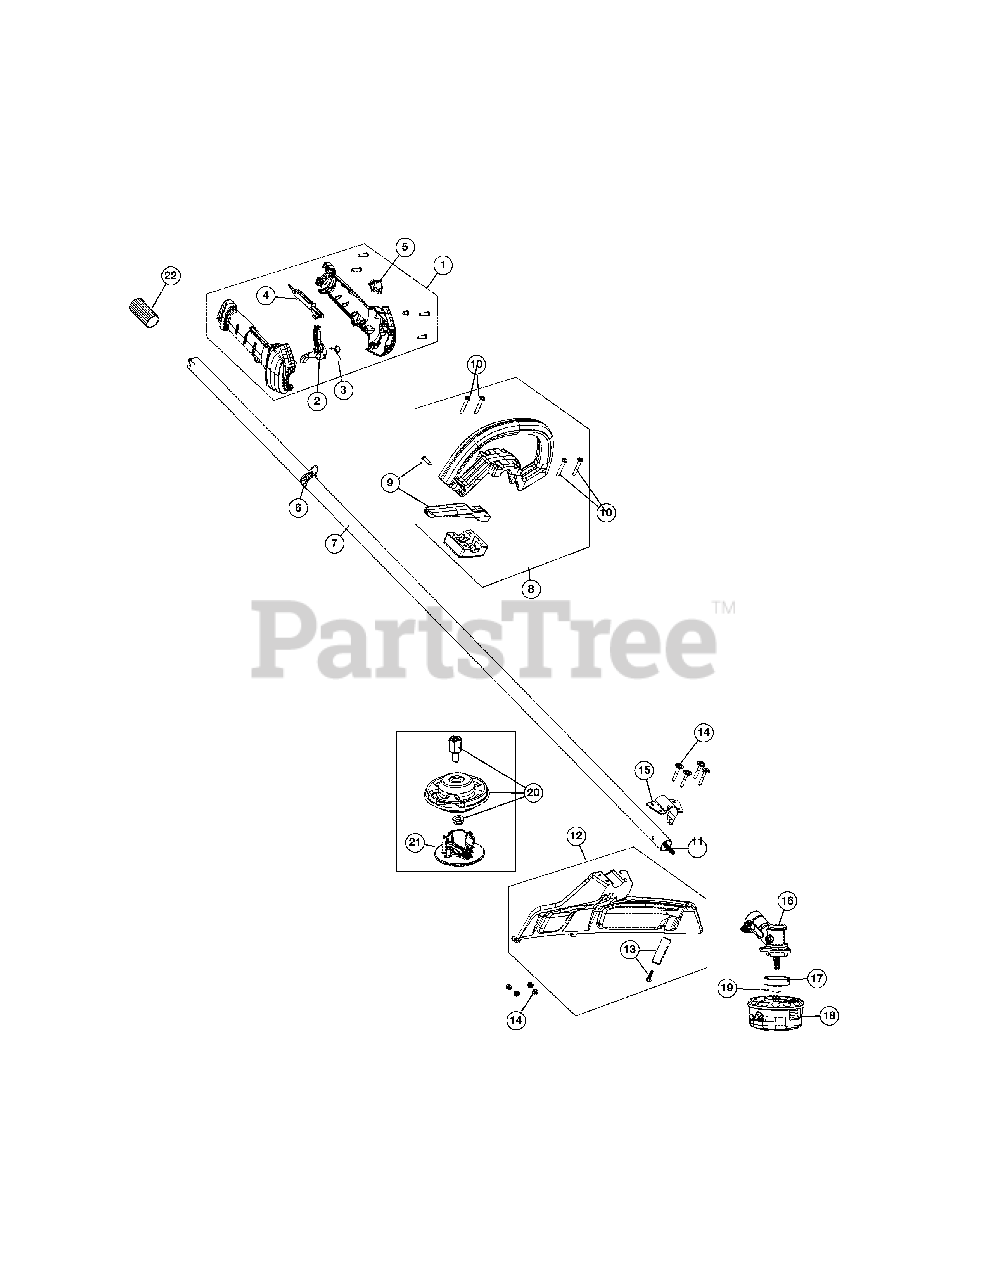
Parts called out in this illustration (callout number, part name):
1	Throttle Housing Assembly (Incl Ref No. 2-5)
2	Throttle Trigger
3	Spring
4	Throttle Lock-out
6	Shoulder Strap Clip
7	Driver Shaft Housing
8	D-Handle Assembly (Incl Ref No. 9 & 10)
9	Barrier Bar Assembly
11	Flexible Drive Shaft
12	Shield Assembly (Incl Ref No. 13)
13	Blade Assembly
15	Guard Mounting Bracket
16	Gearbox
17	Gearbox Spacer
18	Cutting Head Assembly
19	Palnut
20	Fixed Line Head
21	Glide Plate
22	Tube Spacer
